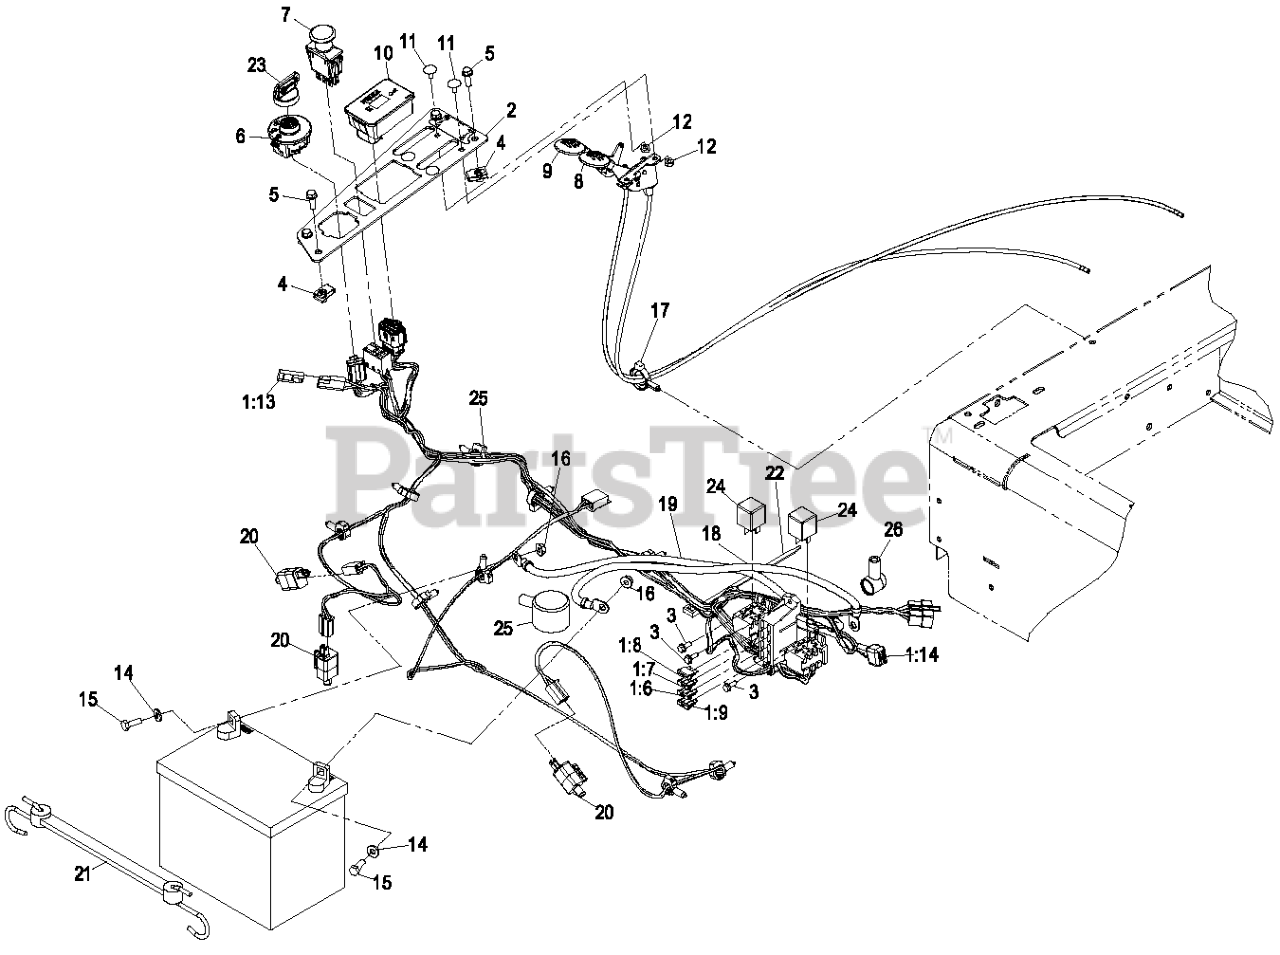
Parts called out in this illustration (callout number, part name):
1	HARNESS-WIRE
1:6	FUSE-BLADE, 25 AMP
1:7	FUSE-BLADE TYPE, 20 AMP
1:8	FUSE-BLADE, 15 AMP
1:9	FUSE-BLADE, 10 AMP
1:13	CAP-PLUG
1:14	DIODE-TVS
3	SCREW-TAPTITE
4	Nut, Retainer-Panel 1/4-20
5	SCREW-HWH
7	SWITCH-PTO
8	CONTROL-THROTTLE
9	CONTROL,CHOKE
11	BOLT-CARR
12	NUT-LOCK, NI
14	WASHER-FLAT
15	SCREW-HH
17	CLAMP-HOSE
18	POSITIVE BATTERY CABLE AS
19	CABLE-GROUND, NEGATIVE
21	HOLDDOWN-BATTERY
22	TIE-PLASTIC
23	KEY-IGNITION
25	INSULATOR-BATTERY
26	INSULATOR-SOLENOID
